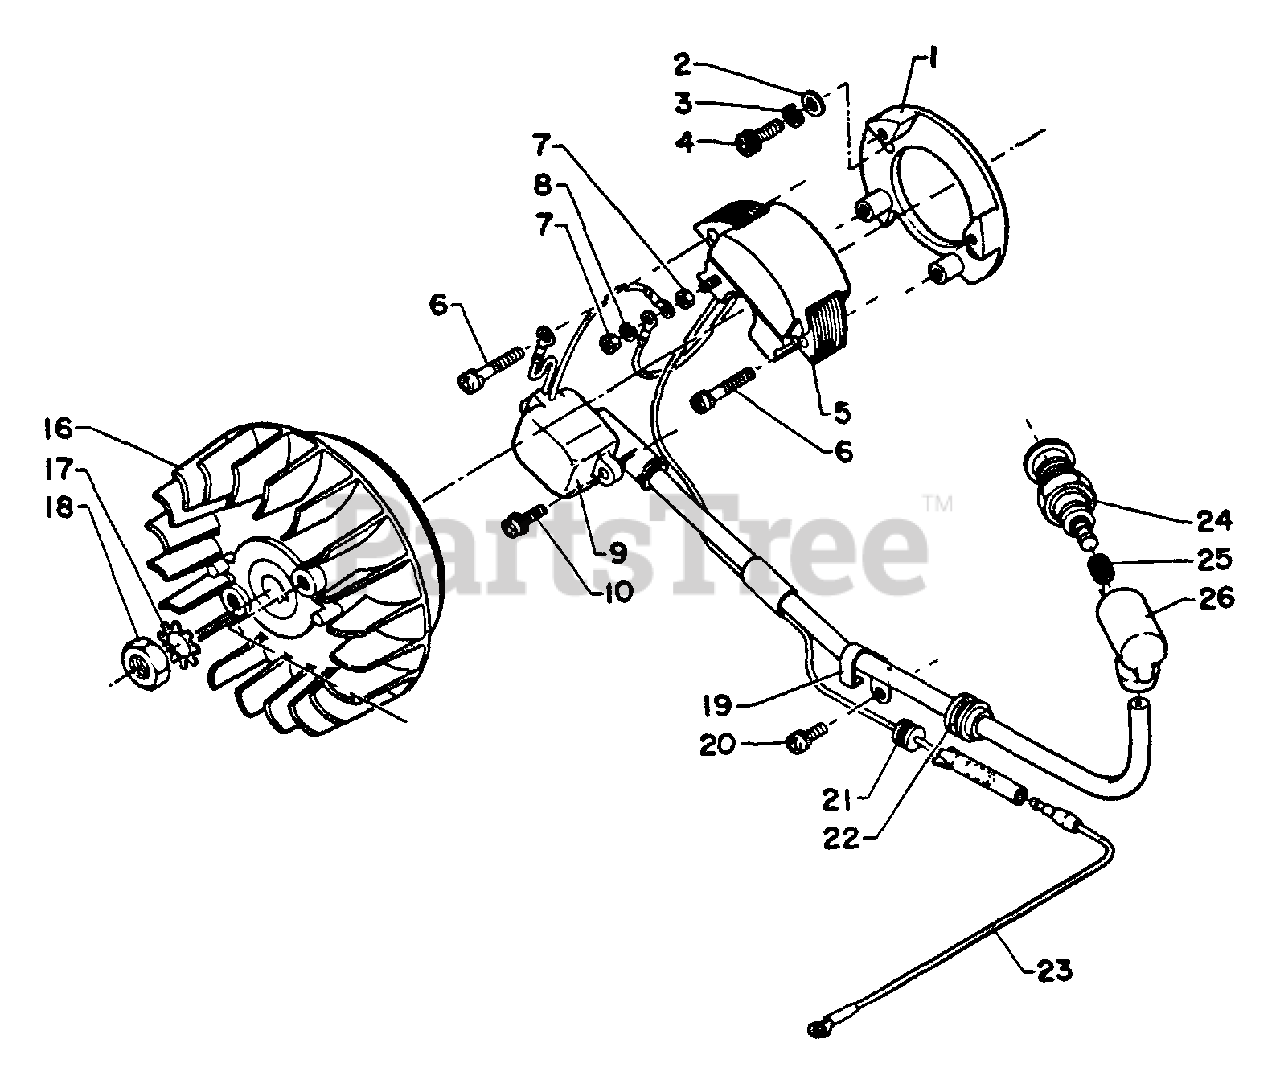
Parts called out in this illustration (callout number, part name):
1	PLATE, STATOR
2	WASHER, FLAT 5.5×10×0.8
3	WASHER, SPRING 5
4	SCREW - 5×15
5	COIL, IGNITION
6	SCREW 4×25
7	NUT 3 MM
8	SCREW 4×25
8	LOCKWASHER - 3
9	COIL, IGNITION
10	SCREW 4×14
16	FLYWHEEL
17	WASHER, LOCK
19	CLIP, CORD
20	SCREW 4×10
21	GROMMET
23	LEAD - GROUND
24	SPARK PLUG - BPM7A
25	TERMINAL, SPARK PLUG CAP
26	CAP, SPARK PLUG
